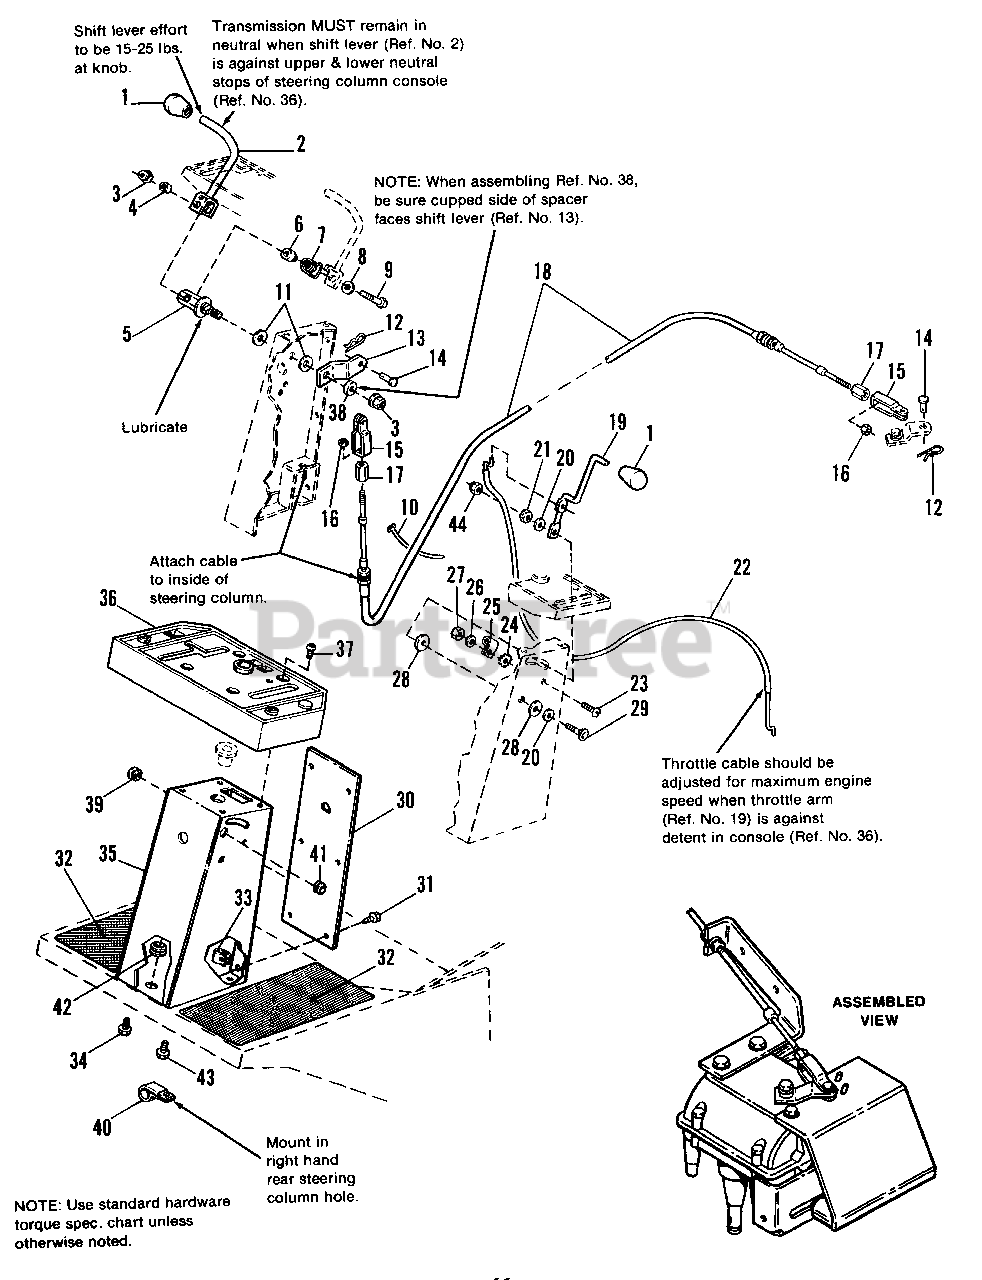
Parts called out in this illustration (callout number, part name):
1	KNOB, Control
2	ROD ASSY., Shift
3	NUT, Hex, Fiber Lock, 5/16-18
5	PIVOT, Shift (Incl. Ref. No. 38)
7	SPRING, Torsion
8	WASHER, Flat, 5/16
9	CAPSCREW, Hex Head 5/16-18 x 2 G5
10	TIE, Self-Locking
11	WASHER, Nylon, 33/64 x 1
12	PIN, Quick
13	LEVER, Shift
16	NUT, Special, #10-32
17	NUT, Collar
18	CABLE, Transmission
19	THROTTLE ARM
20	WASHER, 1/4
21	LOCKNUT, 1/4-20
22	CABLE, Throttle
23	SCREW, Rd. Hd., #10-32 x 1/2
24	LOCKWASHER, Ext. Tooth, #10
25	CLIP, Throttle Cable
26	WASHER, #10
27	NUT, #10-32
28	WASHER, Nylon, 17/64 x 3/4 x 7/8
29	CARRIAGE BOLT, 1/4-20 x 1
30	PANEL, Steering Column
31	SCREW, Hex, Type AB-#14, 1/4-14 x 5/8
33	SPEED NUT, "U" Type, #14
34	SCREW, Taptite, 5/16-18 x 1/2
35	COLUMN ASSY., Steering (1691654)
35	COLUMN ASSY., Steering (1691658)
36	CONSOLE, Steering Column
37	SCREW, Taptite, 1/4-20 x 3/4
38	SPACER, Shift Lever
43	SCREW, Taptite, 5/16-18 x 3/4
44	NUT, Hex, Esna Lock, 1/4-20
